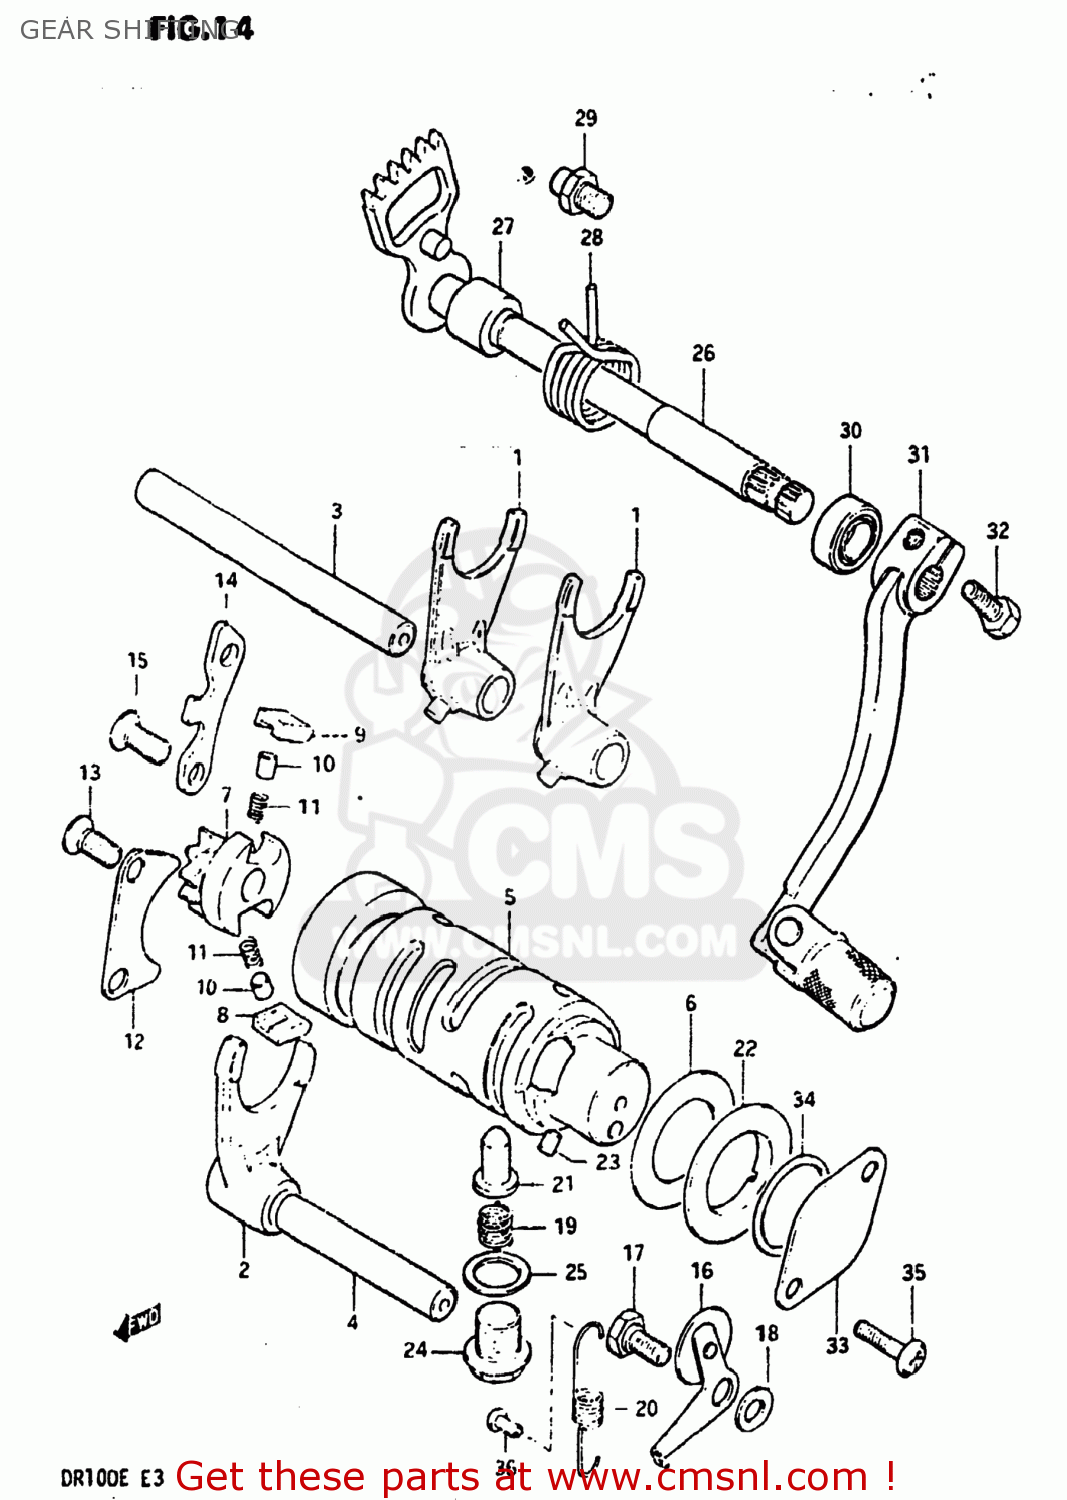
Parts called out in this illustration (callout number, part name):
1	FORK,GEAR SHIFT NO.1
2	FORK,GEAR SHIFT NO.3
3	SHAFT,GEAR SHIFT FORK
4	SHAFT,GEAR SHIFT FORK
5	CAM,GEAR SHIFT
6	WASHER,THRUST
7	RETAINER,GEAR SHIFT CAM
8	PAWL,GEAR SHIFT NO.1
9	PAWL,GEAR SHIFT NO.2
10	PIN(5X8)
11	SPRING
12	LIFTER,GEAR SHIFT PAWL
13	SCREW
14	GUIDE,GEAR SHIFT CAM
15	SCREW
16	STOPPER,GEAR SHIFTING
17	BOLT
18	WASHER
19	SPRING
20	SPRING
21	STOPPER,GEAR SHIFT CAM NO.2
22	PLATE,GEAR SHIFT CAM STOPPER
23	PIN 4X6
24	PLUG (14X12)
25	GASKET(14X19.2X2) (NAS)
26	SHAFT,GEAR SHIFT
27	SPACER(12X20X15.3)
28	SPRING
29	STOPPER,GEAR SHIFT CAM
30	OIL SEAL
31	LEVER ASSY,GEAR SHIFT
32	BOLT
33	CAP,GEAR SHIFT CAM PIVOT
34	O-RING (D:2.4 ID:26.2)
35	SCREW
36	RIVET
